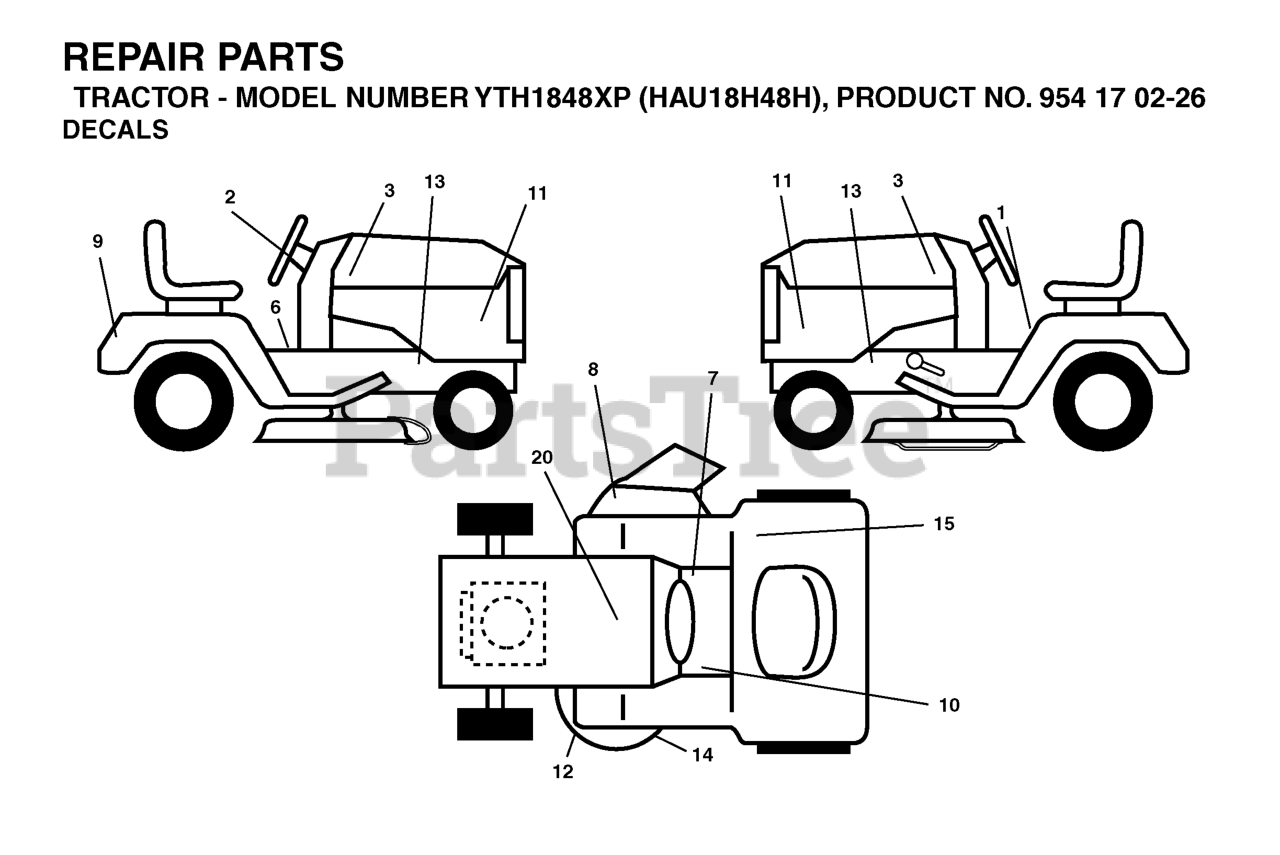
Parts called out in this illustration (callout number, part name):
1	DECAL READ OWNER'S MAN SYMS
2	DECAL.STEERING.HUSQ.BLUE
3	DECAL.HOOD.HUSQVARNA.INTERNATI
6	DECAL
7	DECAL PARK BRAKE
8	DECAL.INTERNATIONL.CUTFINGER
10	DECAL
12	DECAL CLUTCH/BRAKE
14	DECAL V-BELT SCHEMATIC
15	DECAL
20	DECAL BTRY SYMBOLS
